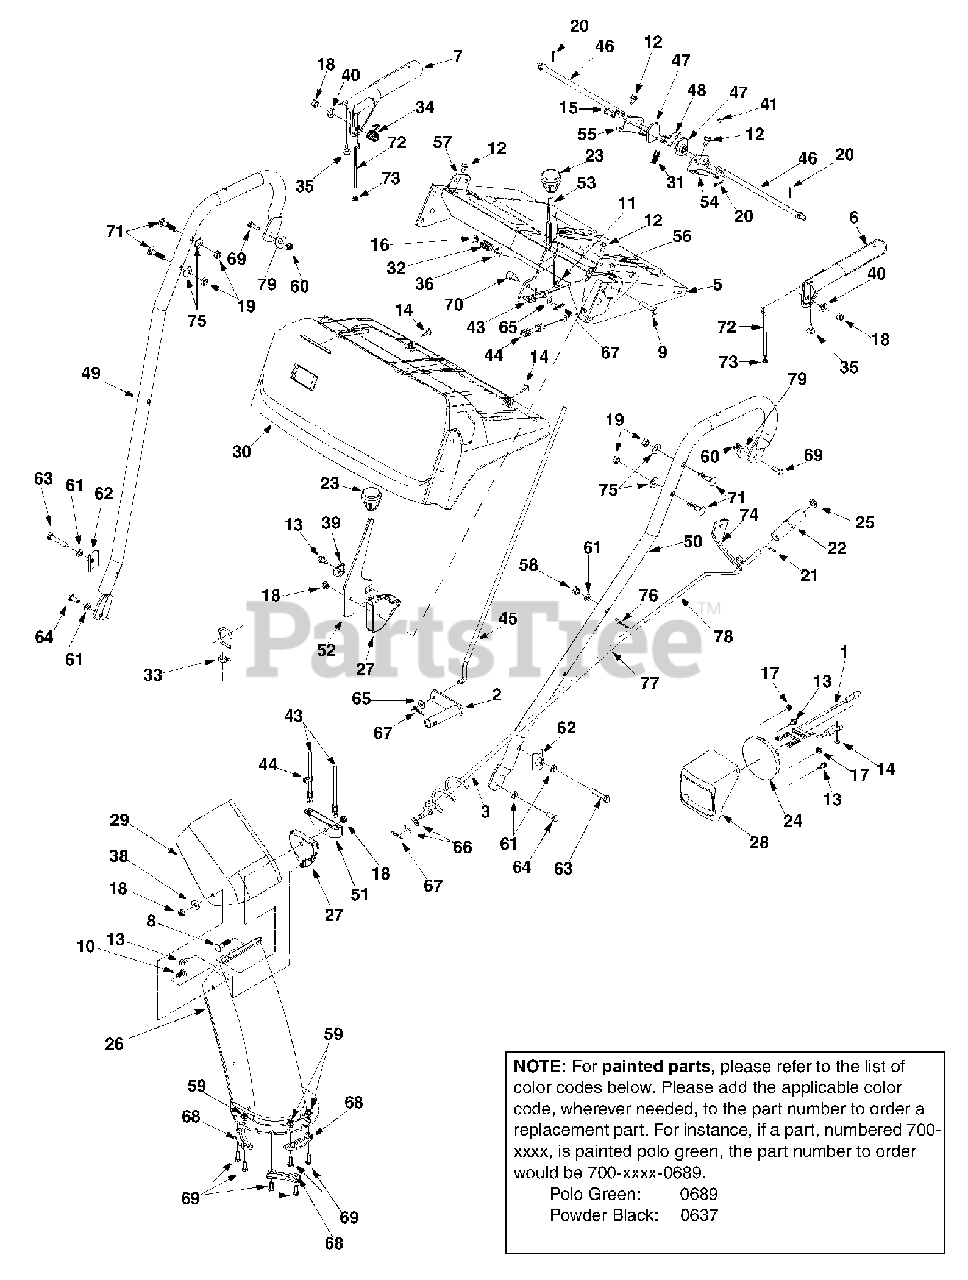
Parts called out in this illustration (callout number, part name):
1	Harness for Headlight
6	Handle Assembly Engagement LH
7	Handle Assembly Engagement RH
8	Carriage Bolt 5/16-18 x 1.50
9	Hex Bolt 5/16-18 x 1.5
10	Carriage Bolt 5/16-18 x.75
11	Hex Screw 3/8-24 x 1.5
12	TT Screw 1/4-20 x 0.5"
13	Hex AB Tap Screw 1/4 x .62
14	Hex B-Tapp Screw #10-16 x .62
15	Clevis Pin
16	Hex Ins. Lock Nut 3/8-24
17	Self-Threading Nut
18	Lock Nut 5/16-18
19	Lock Nut 5/16-18
20	Cotter Pin
21	Roll Pin
22	Chute Crank Knob
23	Shift Knob
24	Headlight
25	Push Cap
26	Lower Chute
27	Cable Guide
28	Headlight Bezel
29	Upper Chute
30	Handle Panel
31	Compression Spring
32	Compression Spring
33	Cable Control Wire
34	Torsion Spring
35	Rubber Bumper
36	Bell Washer .380 x .880 x .062
38	Special Washer
39	Special Washer
40	Flatwasher 3/8" I.D. x 1.25" O.D.
43	Chute Deflector Control Cable
44	Chute Deflector Cable w/ Clip
45	Shift Rod
46	Cam Rod
47	Cam Handle Lock
48	Pawl Handle lock
58	Hex Nut 5/16-18 Thd.
59	Hex Flange Locked Nut 1/4-20 Thd.
60	Hex Nut 1/4-20
61	Lock Washer 5/16
62	Handle Tab
63	Hex Bolt 5/16-18 x 1.75 Gr.5
64	Hex Bolt 5/16-18 x 0.75" Gr. 5
65	Flat Washer 5/16
66	Flat Washer 3/8 x .738 x .063"
67	Hairpin Clip
68	Chute Flange Keeper
69	Hex Bolt 1/4-20 x 0.75" Gr.5
70	Ferrule
71	Carriage Bolt 5/16-18 x 1.50
72	Z Fitting
73	Hex Nut #10-24
75	Cupped Washer
76	Hairpin Clip
77	Spacer
79	Bell Washer
